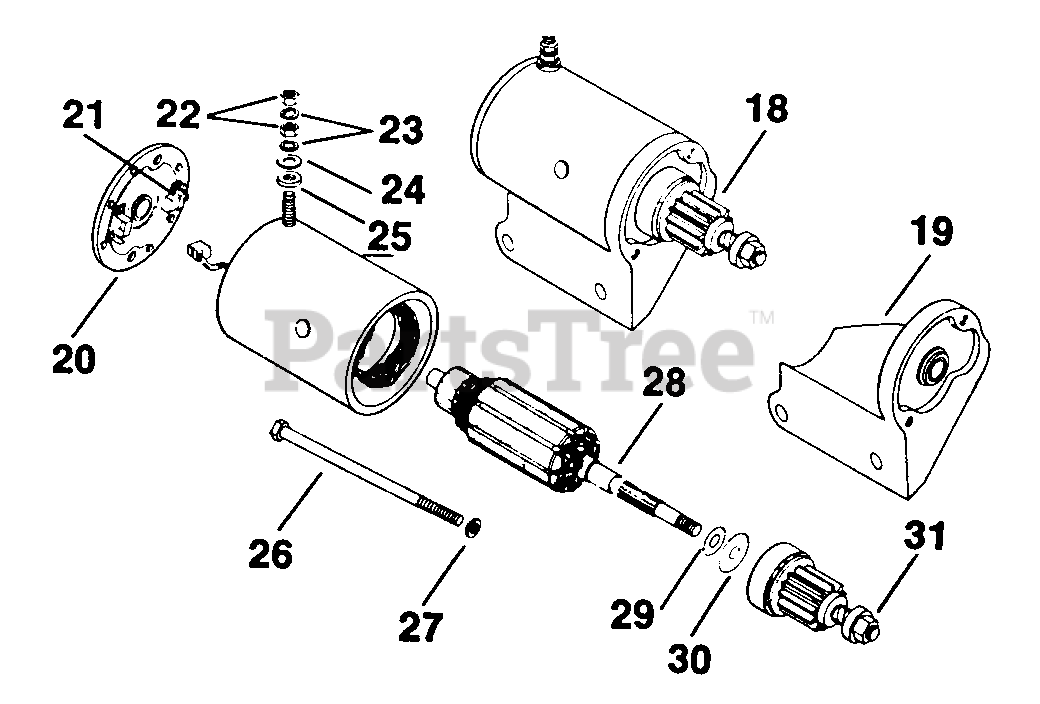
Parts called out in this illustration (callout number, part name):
18	KIT, STARTER
21	KIT - DISCONTINUED
22	KIT - USE 237761
24	KIT - USE 237761
26	BOLT - DISCONTINUED
27	KIT - USE 237761
28	ARMATURE - DISCONTINUED
31	DRIVE - DISCONTINUED
